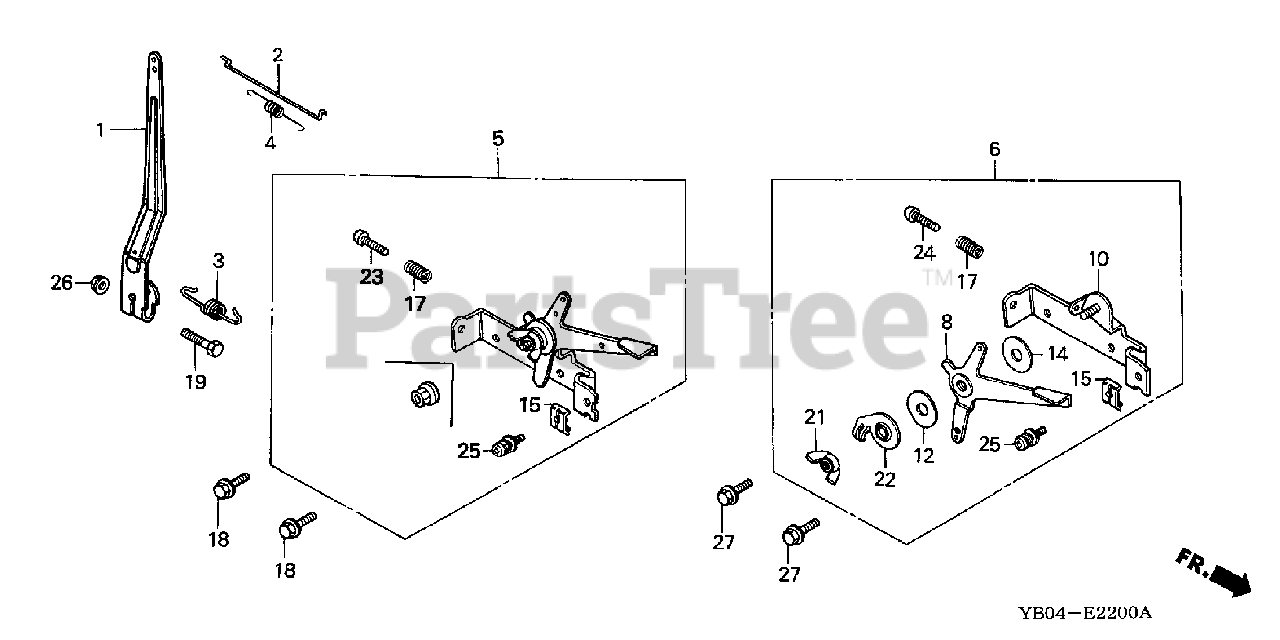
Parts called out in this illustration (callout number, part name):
1	ARM, GOVERNOR
2	ROD, GOVERNOR
3	SPRING, GOVERNOR
4	SPRING, THROTTLE RETURN
5	CONTROL ASSY. (STD)
15	HOLDER, CABLE
17	SPRING, CONTROL ADJUSTING
18	BOLT, FLANGE (6X12) (CT200)
19	BOLT, GOVERNOR ARM
23	SCREW, PAN (5X25)
25	SCREW, PAN (5X16)
26	NUT, FLANGE (6MM)
